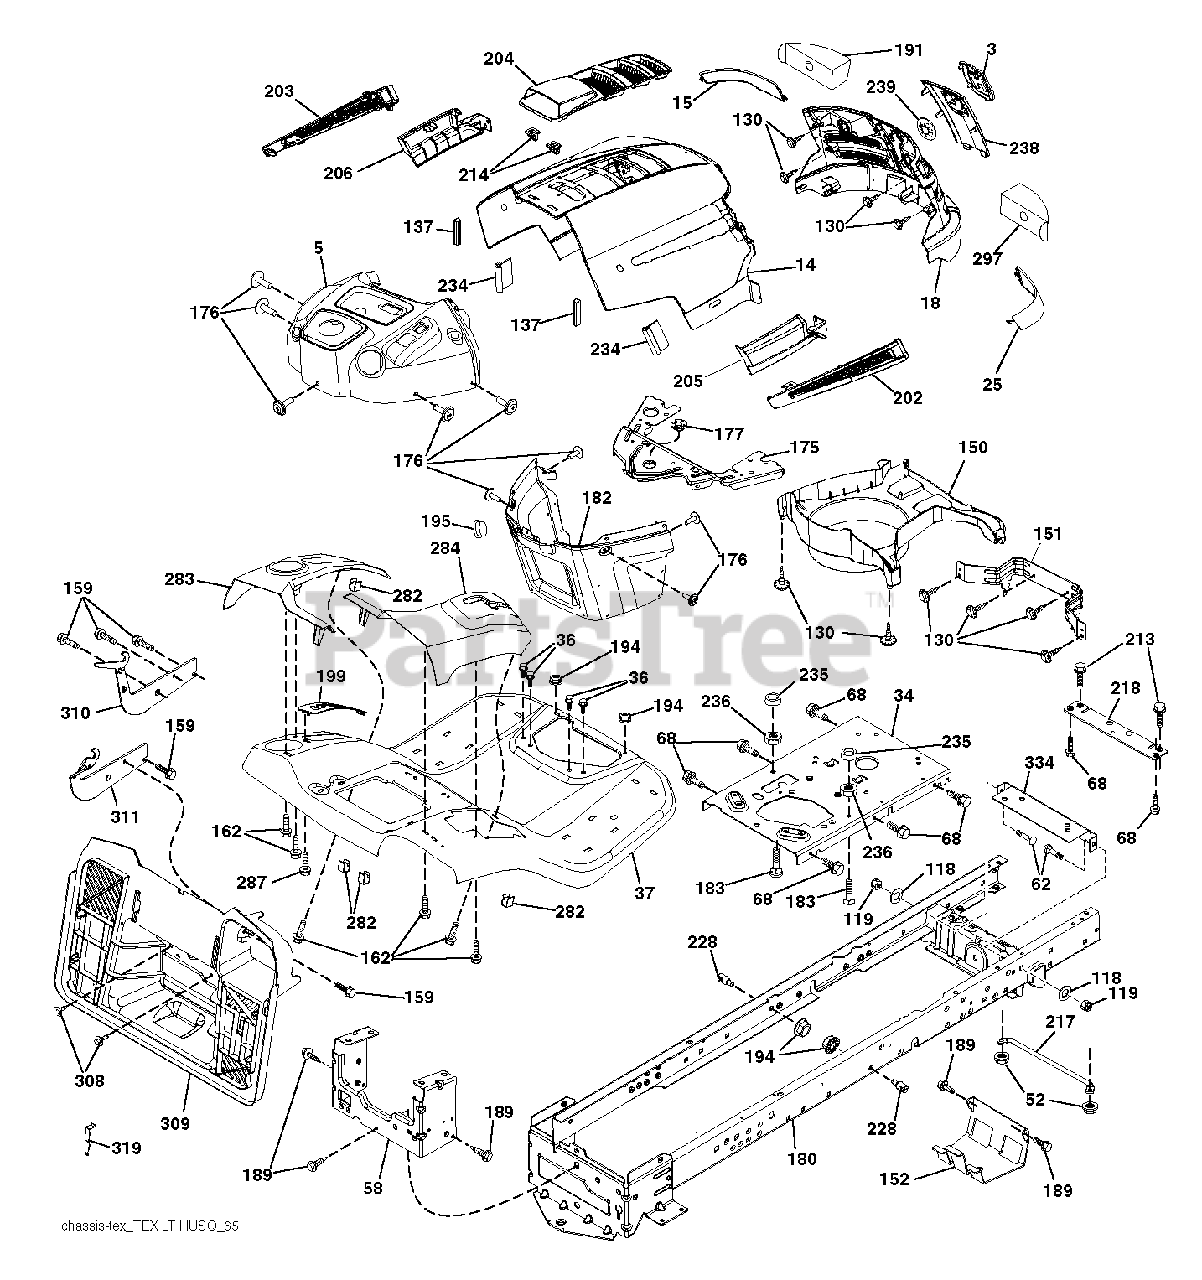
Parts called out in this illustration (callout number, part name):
3	LOGO.HUSQ.GT.LT.CROWN.H
5	SUBASM.DASH.UPPER.W/BUMPER
14	HOOD.HUSQVARNA.LT.ORANGE
15	LENS.HUSQVARNA LT.RH
18	GRILLE.SVC.HUSQVARNA.GREY
25	LENS.HUSQVARNA LT.RH
34	PLATE.ENGINE.10GA.CRD.GENII
36	SCREW 5/16"
37	FENDER.TEX.SRD.CRD.BASE
52	LOCKNUT
58	DRAWBAR UPPER 2PC SMALL FENDER
62	BOLT D
68	SCREW LT
118	WASHER
130	SCREW.#10 X 0.750.BOS
137	BUMPER DASH
151	BRACKET PIVOT
152	SHIELD.BROWNING.W/TEX
159	SCREW, 3/8-16X3/4
162	SCREW.HI-LO.CONSOLE
175	CROSSMEMBER
176	SCREW.#10-24X5/8.RN.QU
177	BUSHING STEERING
180	CHASSIS.WLDMNT.14GA.2PC.18".TI
182	DASH.LOWER.PREDATOR LT
183	BOLT.5/16-18X1-1/4 FULL THD
189	SCREW
191	INSERT.REFLECTIVE.RH.
194	NUT LOCK HEX FLANGE 5/16-18
195	PLUG.TEX.DASH.SVC.MINDER.GREY
199	PLATE DECK LIFT
202	VENT.SIDE.HUSQVARNA.LT.RT
203	VENT.SIDE.HUSQVARNA.LT.LFT
204	SUBASM.TOP.VENT.HUSQ.LT
205	SKIRT.SIDE.HUSQVARNA.LT.RT
206	SKIRT.SIDE.HUSQVARNA.LT.LEFT
213	BOLT
214	CLIP.RETAINER.TINNER.
217	ROD.PIVOT.HOOD
218	X-PIECE.HOOD.STOP.NON/
228	STUD.FASTNER.W/ANTI-ROTATE
234	BUMPER.HOOD.TEX.HUSQVARNA
235	SPACER FENDER
236	NUT.CENTERLOCK.5/16-
238	TRIM.HUSQ LT.668
282	CLIP.RETAINER.CONSOLE.LT.HUSQ
283	CONSL.DECKLIFT.LH.SRD.TEX.CRD
284	CONSL.SHIFT.GEAR.RH.SRD.GREY
287	SCREW 1/4X20
297	INSERT REFLECTIVE
308	BOLT, 5/16-18 X 1 3/4
309	BACKPLATE.BAGGER.V2.SRD
319	BRACKET.ACTUATOR.BAGGER.SRD
334	BRACKET.ENGINE
